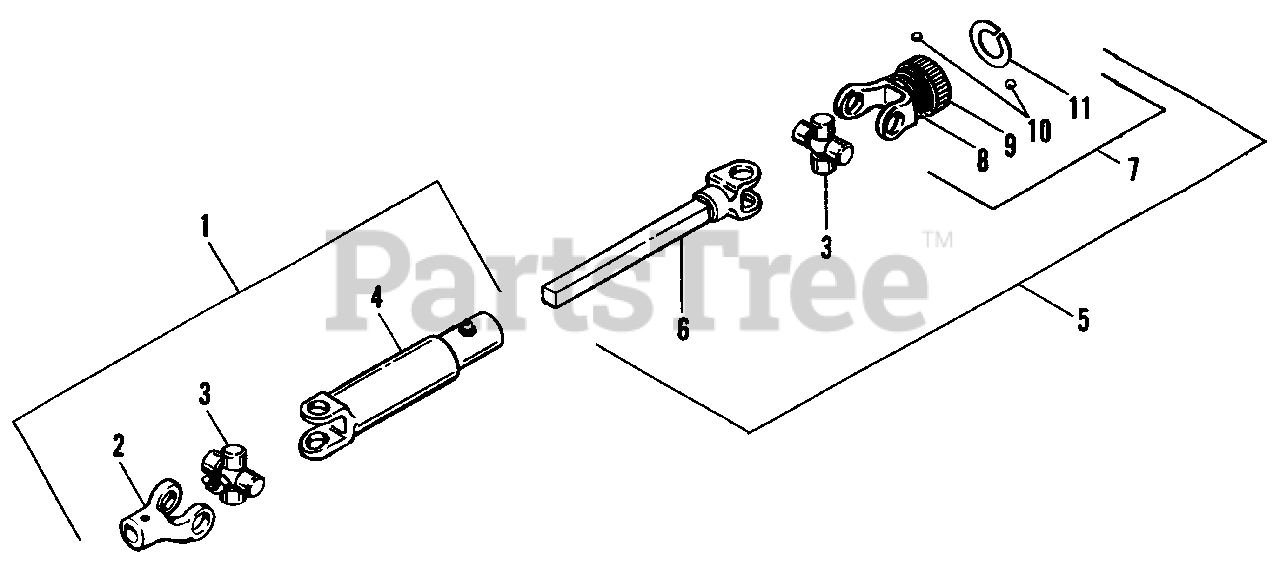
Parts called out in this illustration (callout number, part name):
1	REAR HALF ASSY., Drive Shaft
3	JOURNAL ASSY.
4	YOKE & TUBE ASSY.
5	FRONT HALF ASSY., Drive Shaft
6	YOKE & SHAFT ASSY.
7	YOKE ASSY.
8	SPRING
9	SLIDE LOCK
10	BALL
11	SNAP RING
